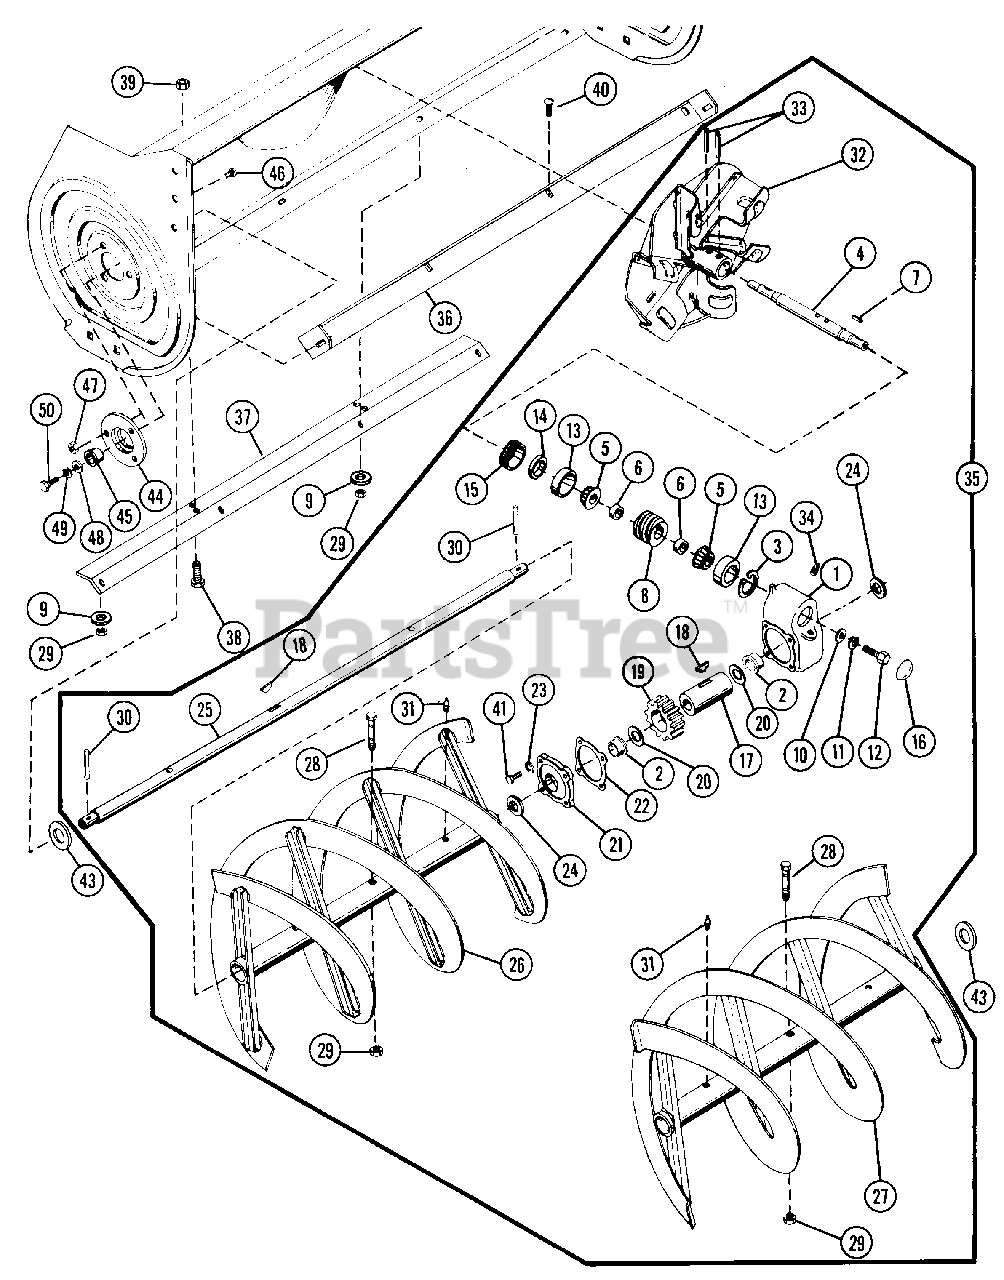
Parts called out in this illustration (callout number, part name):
1	GEAR CASE
2	BUSHING, FLANGE 1.62X1.87X11
3	SNAP RING, INTERNAL
4	WORM SHAFT
5	BEARING CONE, .75 I.D.
6	BEARING SPACER
7	KEY, STRAIGHT SAE 1035
8	WORM
9	WASHER, .406X.812X.065
10	WASHER, .344X.688X.065
11	WASHER, LOCK 3/8
12	BOLT, HEX 5/16-18X.75
13	BEARING CUP
14	SEAL
15	ADJUSTMENT PLUG
16	DUST CAP
17	GEAR CASE SHAFT
18	KEY, WOODRUFF 1/4X7/8 HRD #A
19	WORM GEAR
20	WASHER, 1.625X2.500X.012
21	GEAR CASE COVER
22	GASKET
23	WASHER, LOCK 1/4
24	SEAL, 1-5/8 NOM.
25	RAKE SHAFT
26	RIGHT RAKE
27	LEFT RAKE
28	SHEAR BOLT
29	NUT, LOCK 5/16-18
30	PIN, SPRING .187X1.500
31	FITTING, SPIN DRIVE ZERK
32	FAN
33	PIN, ROLL .312X1.75
34	PIPE PLUG
35	BLOWER GEAR CASE ASSEMBLY
36	SCRAPER BLADE
37	BLADE BRACE
38	BOLT, HEX 3/8-16X.75
39	NUT, LOCK 3/8-16
40	BOLT, 3/8-16X.75 RD HD SQ NK
41	BOLT, HEX 1/4-20X.875
43	WASHER, 1.00X1.50X.06
44	BEARING SUPPORT
45	BUSHING, FLANGE 1.00X1.125X.625
46	BOLT, RIB NECK 1/4-20X.50
47	NUT, LOCK 1/4-20
48	WASHER, .307/.327X.734X.065
49	WASHER, LOCK 1/2
50	BOLT, HEX 1/2-13X1.00
